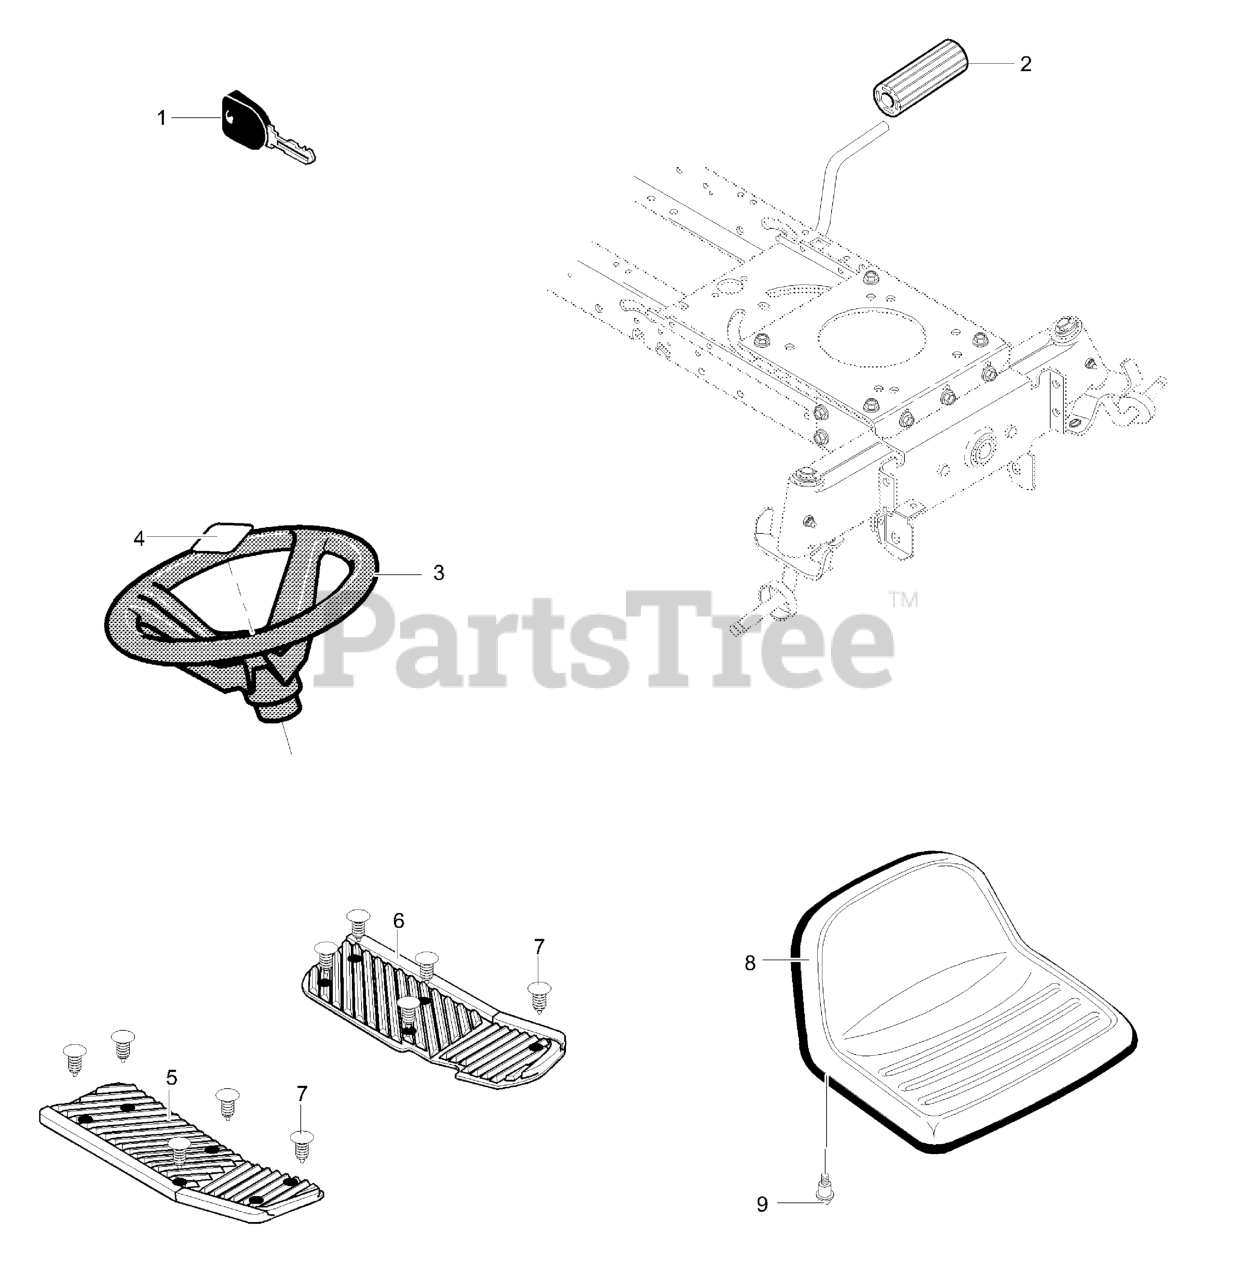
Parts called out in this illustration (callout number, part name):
1	Ignition Key
2	Cover, Pedal Brake/Clutch
3	Steering Wheel
4	Insert, 4-Spoke
5	Footrest Pad RH
6	Footrest Pad LH
7	Ratchet Faastener
9	Shoulder Bolt 5/16-18
